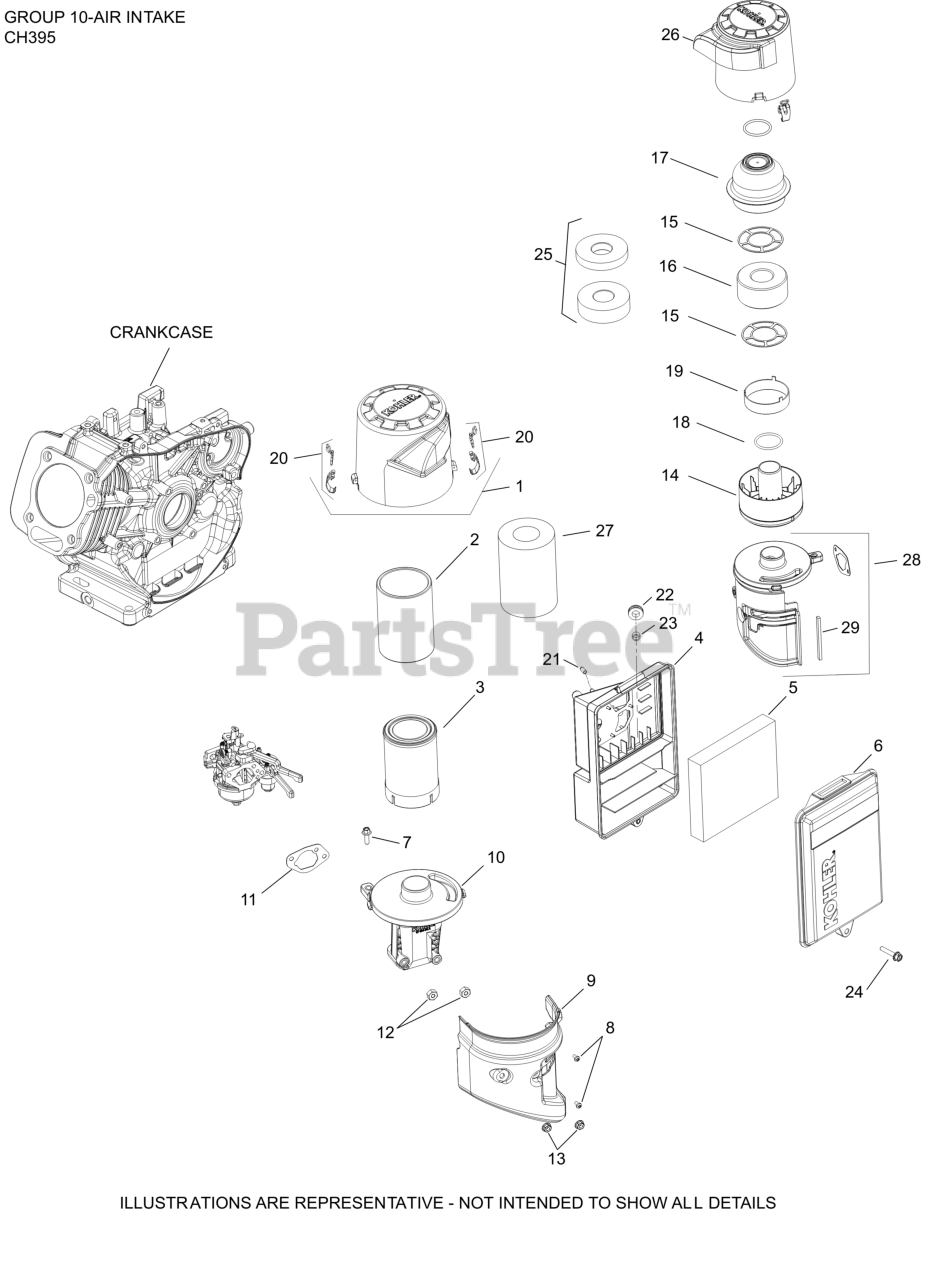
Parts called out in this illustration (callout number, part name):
1	COVER, AIR CLEANR ASSEMBLY
2	ELEMENT, PRE-CLEANER
3	ELEMENT, AIR FILTER
11	GASKET, AIR CLEANER
20	KIT, LATCH CLIP
28	KIT, AIR CLEANER BASE ASSEMBLY
